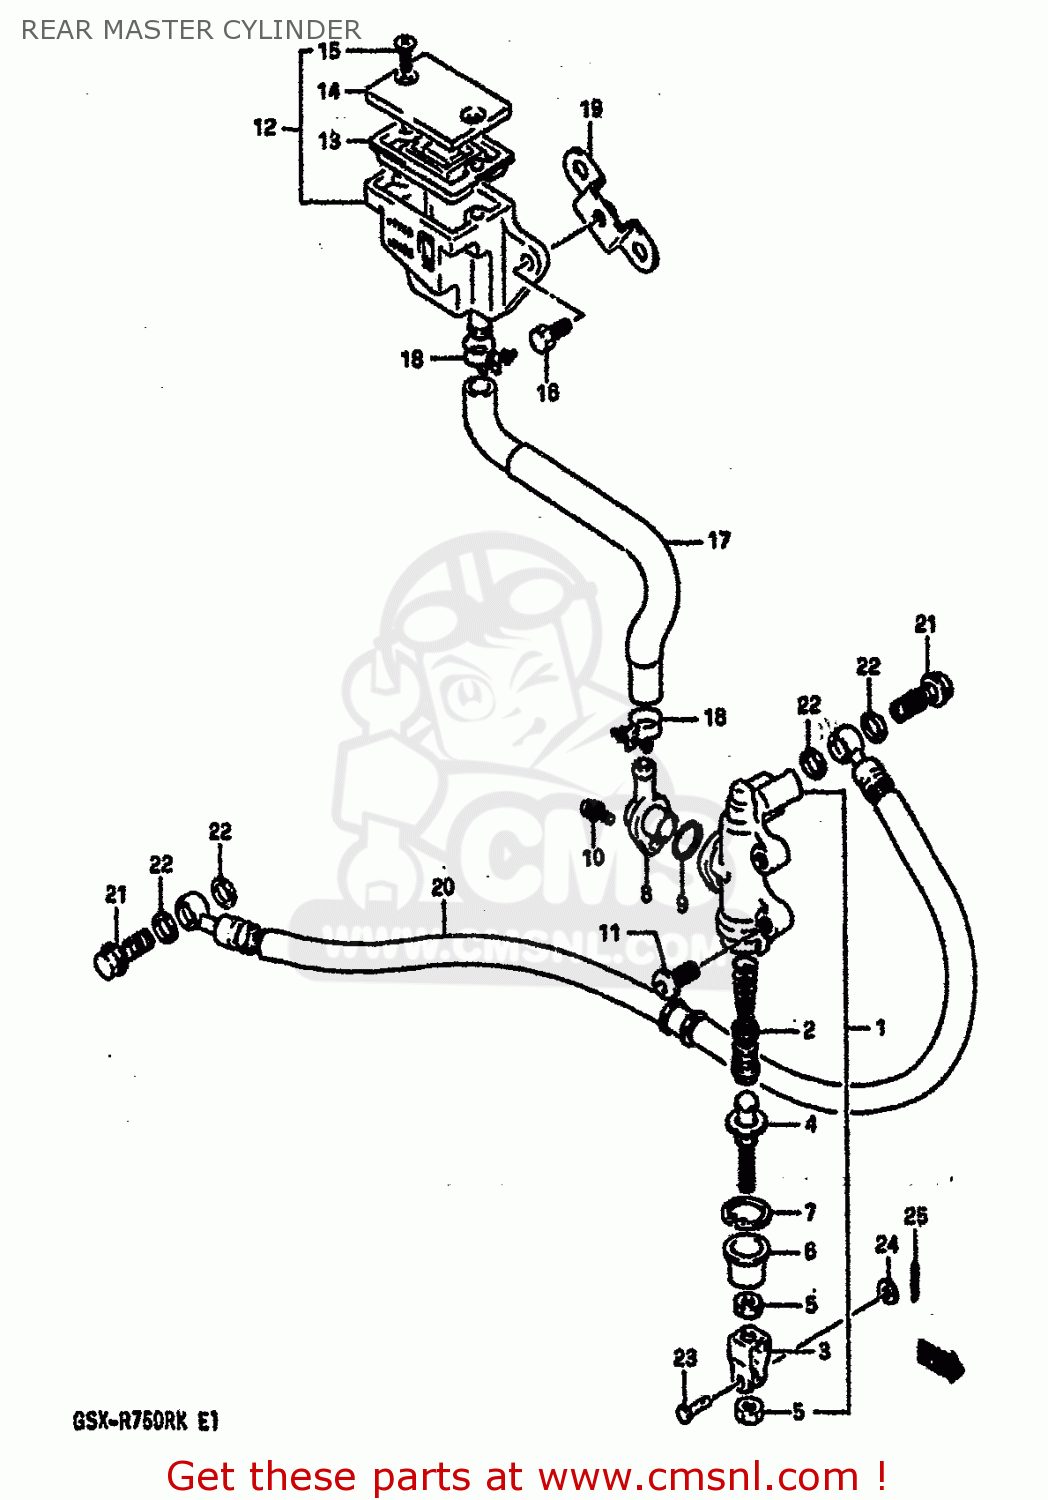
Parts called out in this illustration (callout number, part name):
1	CYLINDER ASSY,RR MASTER
2	PISTON/CUP SET
3	YOKE
4	ROD,PUSH
5	NUT
6	BOOT
7	CIRCLIP
8	CONNECTOR
9	O RING
10	SCREW
11	SCREW(8X22)
12	TANK ASSEMBLY,RESERVOIR
13	DIAPHRAGM
14	CAP
15	SCREW
16	BOLT
17	HOSE,RESERVOIR
18	CLAMP
19	BRACKET,TANK
20	HOSE,REAR BRAKE
21	BOLT UNION
22	WASHER(10X15X1.5)
23	PIN
24	WASHER
25	PIN
